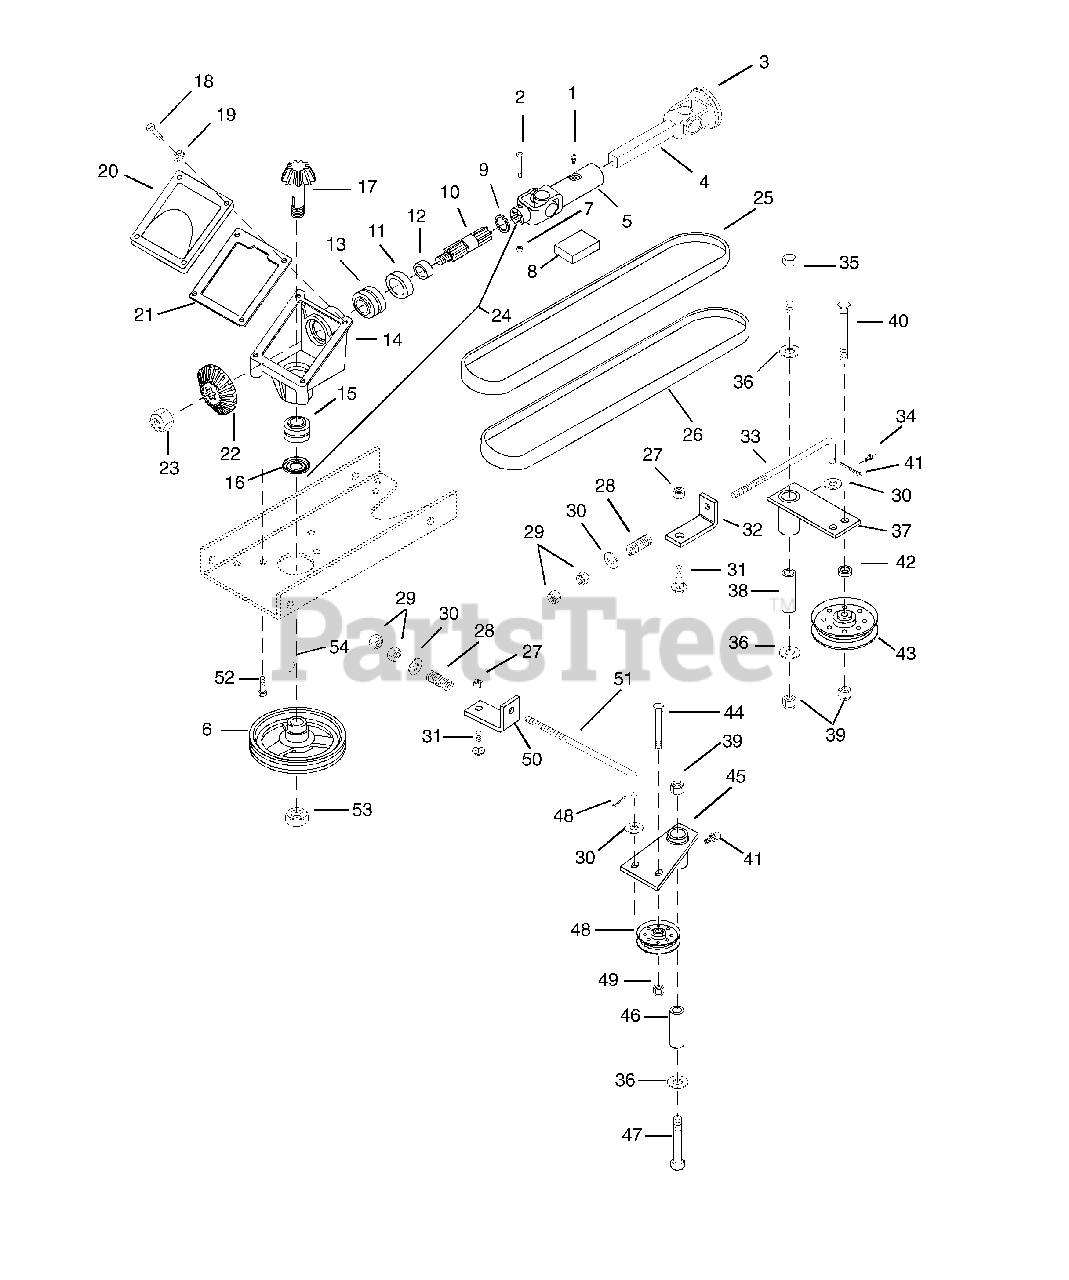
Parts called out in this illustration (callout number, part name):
1	Fitting-Lube .25-28 x .256
2	Bolt-Hex .25-20 x 2.25
3	Q.D. Yoke
4	Shaft-Prop Square Bar
5	Joint-U Female End
6	Pulley-Gearbox
7	Nut-Locking-Nylon .250-20 Grade 2
8	Kit-Repair U-Joint
9	Ring-Retaining 1.106 x .95
10	Shaft
11	Seal 1.250 x 1.983 x .250
12	Bushing Flange 1.00 x 1.25 x 1.25
13	Bearing-Assembly 1.000 x 1.980 x 1.243
14	Casting-Gear Box
15	Bearing-Assembly .75 x 1.781 x 1.499
16	Seal 1.250 x 1.691 x .310
17	Shaft-Pinion Gear
18	Bolt-Hex .25-20 x .50 Grade 5
19	Washer-Lock .250 Reg.
20	Cover-Gear Housing
21	Gasket-Gear Housing
22	Gear-Bevel
23	Nut-Locking-Nylon .75-10 Grade 2
24	Assembly-Drive 50" Mower
25	V-Belt A-Section 58.56 x .516
26	V-Belt 5L Section 70.375 x .438 x .660
27	Nut-Locking-Nylon .375-16 Grade 2
28	Spring-Compression .125 x .78 x 1.00
29	Nut-Hex .375-24 Grade 2
30	Washer-Flat-Steel .406 x .812 x .065
31	Bolt-Hex .375-16 x 1.00 Grade 5
32	Support-Spring "B"
33	Rod-Idler 50 In. Mower
34	Pin-Cotter .06 x 1.0
35	Bolt-Hex .50-13 x 3.75
36	Washer-Flat-Steel .500 x 1.250 x .083
37	Weldment-Idler Pivot "B"
38	Spacer .505 x .855 x 2.50
39	Nut-Locking-Nylon .50-13 Grade 5
40	Bolt-Hex .50-13 x 2.00 Grade 5
41	Fitting-Lube .25-28 x .46
42	Spacer .516 x .875 x .300
43	Idler-Flat-Pulley 6.75 x .510
44	Bolt-Hex .38-16 x 1.75 Grade 5
45	Weldment, Idler Pivot "A"
46	Spacer .562 x .855 x 2.18
47	Bolt-Round Head Square Neck .50-16 x 3.50
48	Pulley-Idler 4.50 x .380
49	Nut-Lock .375-16 Grade A
50	Support-Spring "A"
51	Rod-Idler 40 In. Mower
52	Bolt-Hex .50-13 x 1 Grade 5
53	Nut-Hex-Jam .750-10
54	Key-Woodruff .19 x .63
